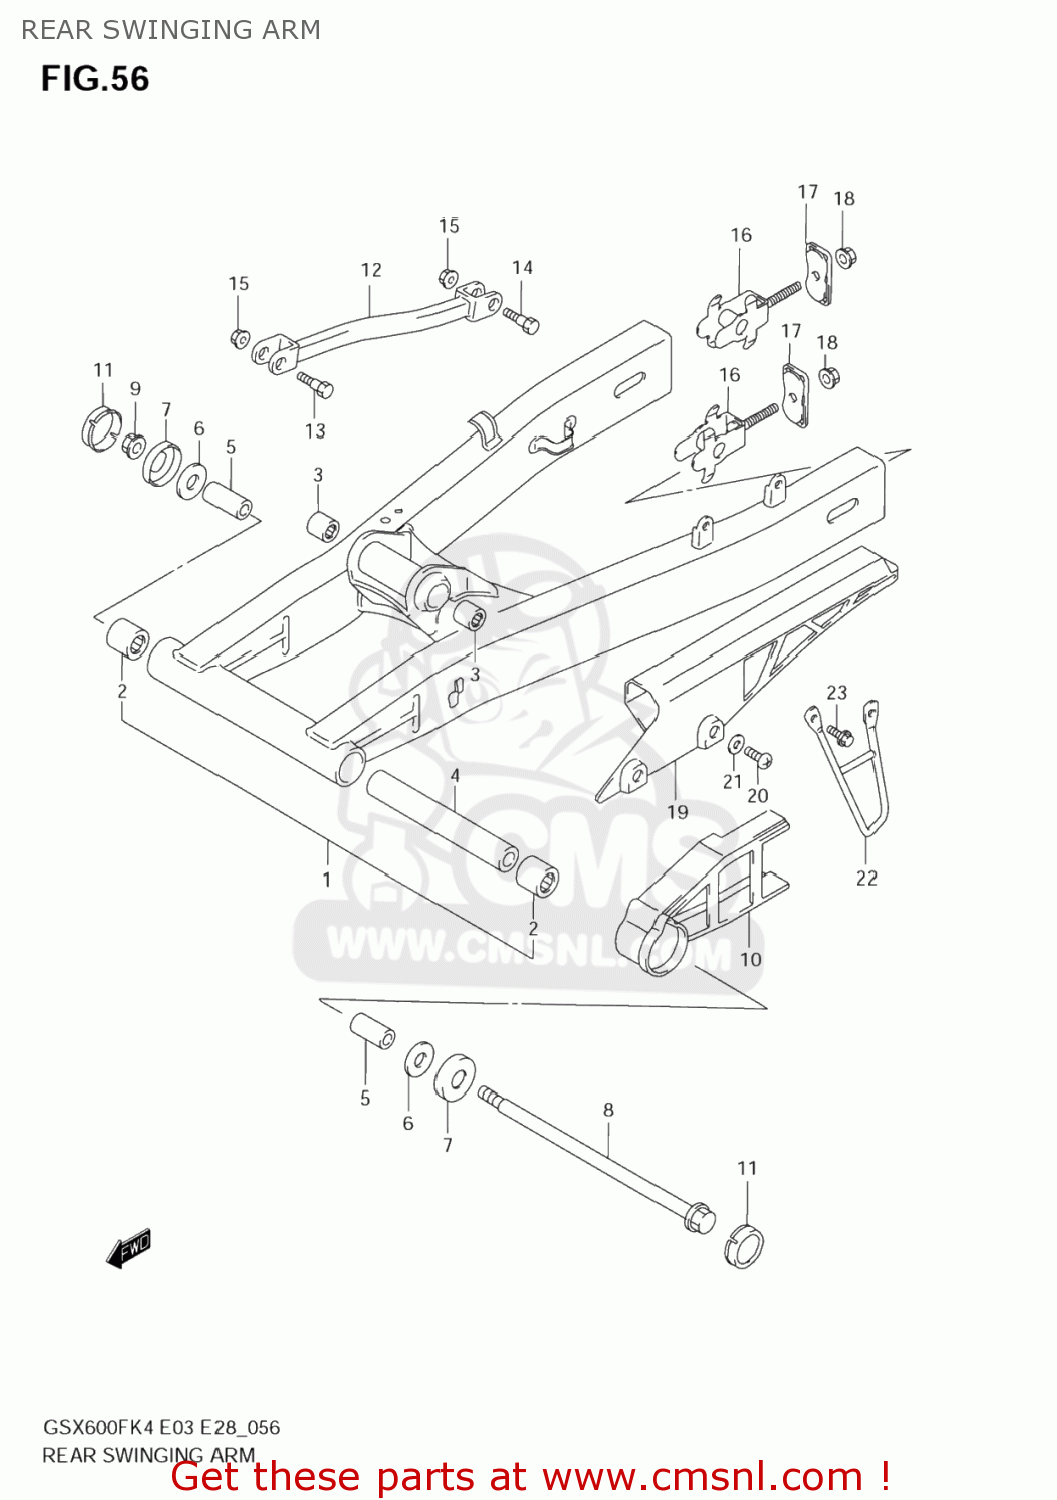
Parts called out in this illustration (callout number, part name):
1	SWINGINGARM ASSY,RR
2	BEARING(22X29X30)
3	BEARING(20X27X23.5)
4	SPACER,RR SWGARM PIVOT CTR
5	SPACER,RR SWGARM PIVOT
6	WASHER
7	COVER,RR SWGARM DUST SEAL
8	SHAFT,RR SWINGINGARM PIVOT
9	NUT
10	BUFFER,CHAIN TOUCH DEFENSE
11	CAP,SWINGINGARM PIVOT
12	TORQUELINK,RR
13	BOLT(10X39)
14	BOLT(10X34)
15	NUT
16	ADJUSTER,CHAIN
17	PLATE,CHAIN ADJ GUIDE
18	NUT
19	CASE,CHAIN
20	SCREW 6X12
21	WASHER
22	GUARD,CHAIN
23	BOLT
